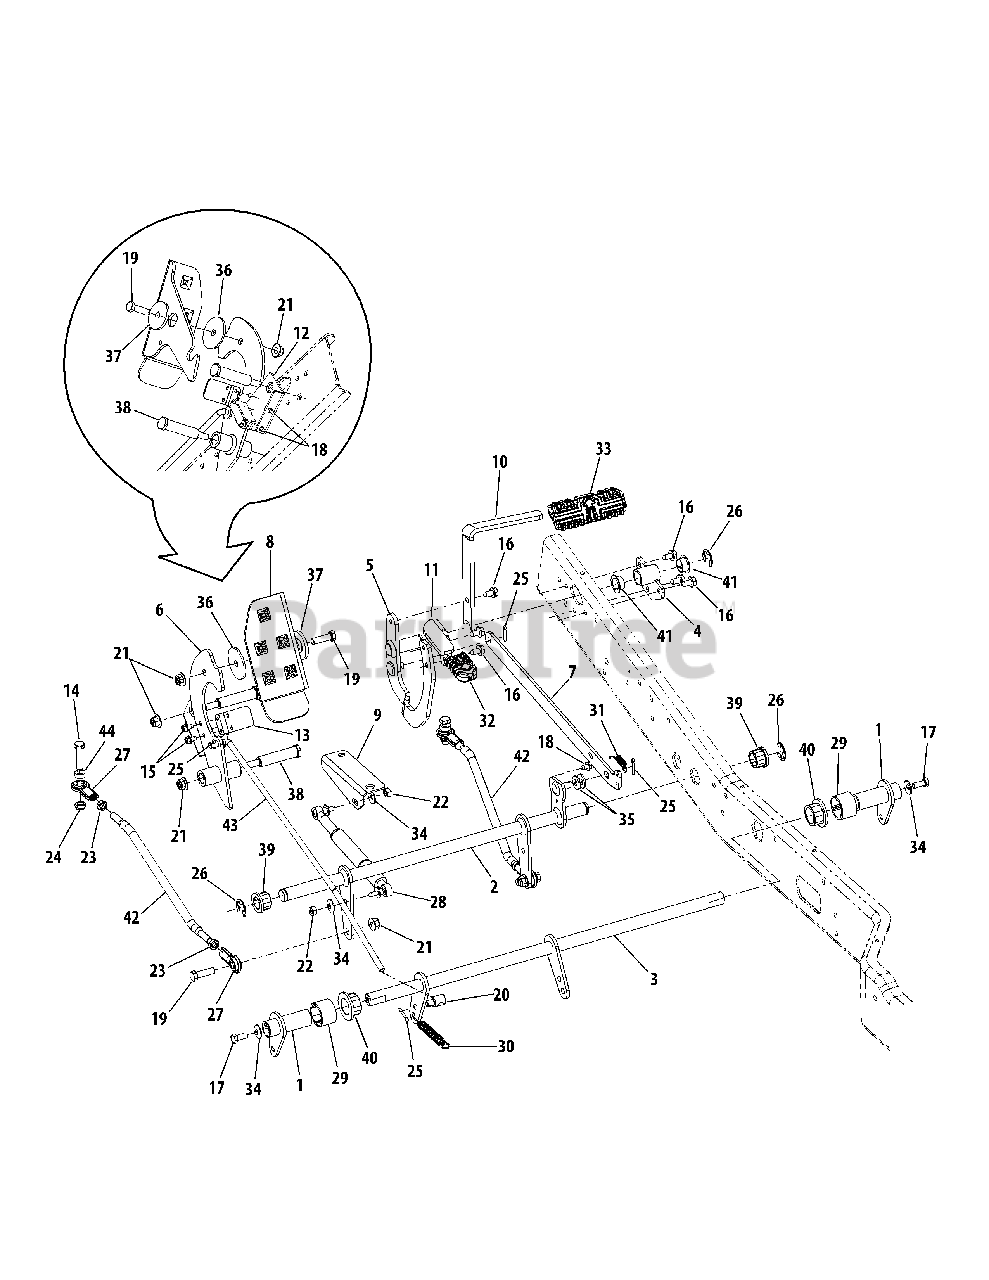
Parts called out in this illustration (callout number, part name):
1	Lever, Brake
2	Shaft, Control Pedal
15	Screw, Hex Wash. Hd. Tapp, 1/4-20 x .5
16	Screw, Hex Wash. Hd. Tapp, 5/16-18 x .625
17	Screw, Hex Cap, 5/16-24 x .75 Gr5 Lock
18	Screw, Hex Wash. Hd. Tapp, 1/4-20 x .375
19	Hex Cap Screw, 3/8-16 1.25 Gr5
20	Ferrule, 3/8-24 x .375
21	Nut, Hex Insert Flange Lock, 3/8-16 GrF
22	Nut, Hex, M8-1.25
23	Nut, Jam, 3/8 -24 Gr5
24	Nut, Hex Insert Jam Lock, 3/8-16 Gr5
25	Pin, Cotter, .125 x .75
27	Ball Joint End . 375
28	Cylinder, Damper
29	Spacer, 1.5 x 1.0 x 1.0
30	Spring, Extension, .5 x 3.97
31	Spring, Extension, .375 x 1.48
32	Pad, Reverse Pedal
33	Pad, Forward Pedal
34	Washer, Belleville, .34 x .872 x .06
35	Washer, Flat, .385 x .87 x .092
36	Washer, Flat, .38 x 2.0 x .12
37	Spacer, Shoulder, .884 x .19
38	Bolt, Shoulder, .625 x 2.515:3/8-16
39	Bearing, Hex Flange, .75 ID
40	Bearing, Hex Flange, 1.25 x .775
41	Bearing, Flange, .75 x 1.125 x .375
42	Rod, Control - Forward/Reverse
43	Rod, Idler
44	Spacer, .38 x .625 x .265
